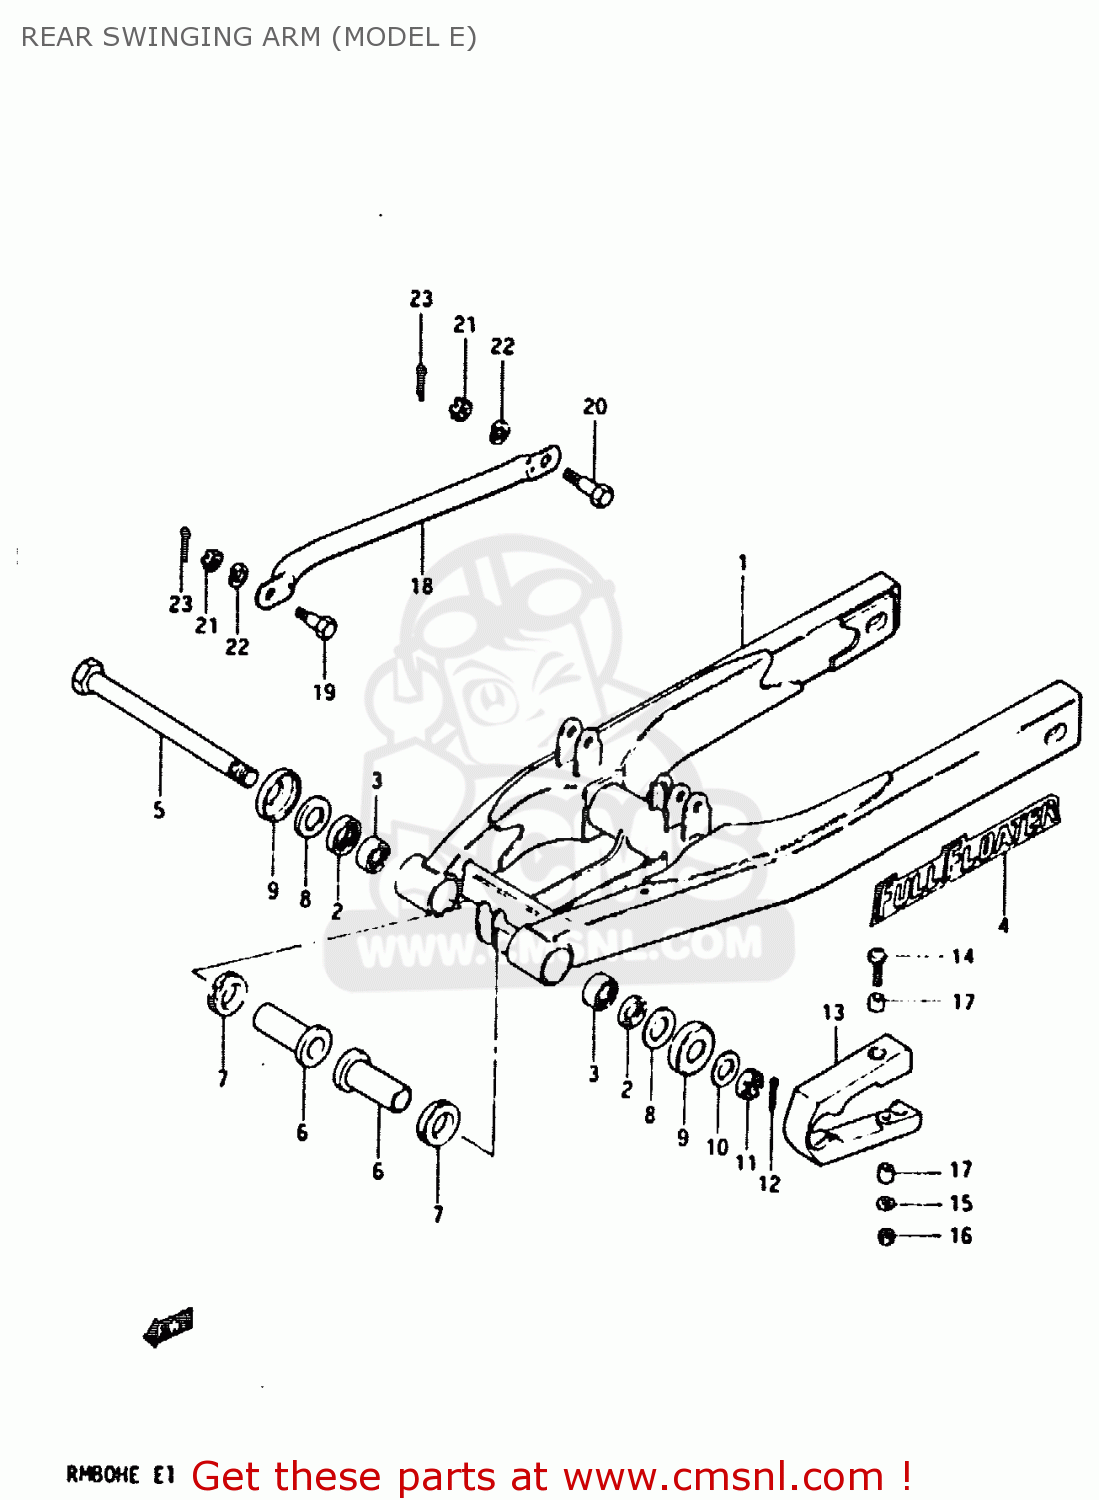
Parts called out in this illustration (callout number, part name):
1	REAR SWINGING ARM SET (GOLD)
2	SEAL,OIL(17X24X3)
3	ROLLER BEARING (17X24X25)
4	EMBLEM
5	SHAFT,REAR SWING ARM
6	SPACER,RR SWGARM PIVOT
7	SEAL,OIL(17X24X5)
8	WASHER
9	COVER,RR SWGARM DUST SEAL
10	WASHER
11	NUT, REAR AXLE
12	COTTER PIN
13	BUFFER,CHAIN TOUCH DEFLECTOR
14	SCREW,CHAIN TOUCH DEFEND
15	WASHER
16	NUT
17	SPACER (5.5X8X4)
18	TORQUC LINK, REAR (GOLD)
19	BOLT(8X22)
20	BOLT(8X21)
21	NUT
22	LOCK WASHER
23	PIN 20X20
